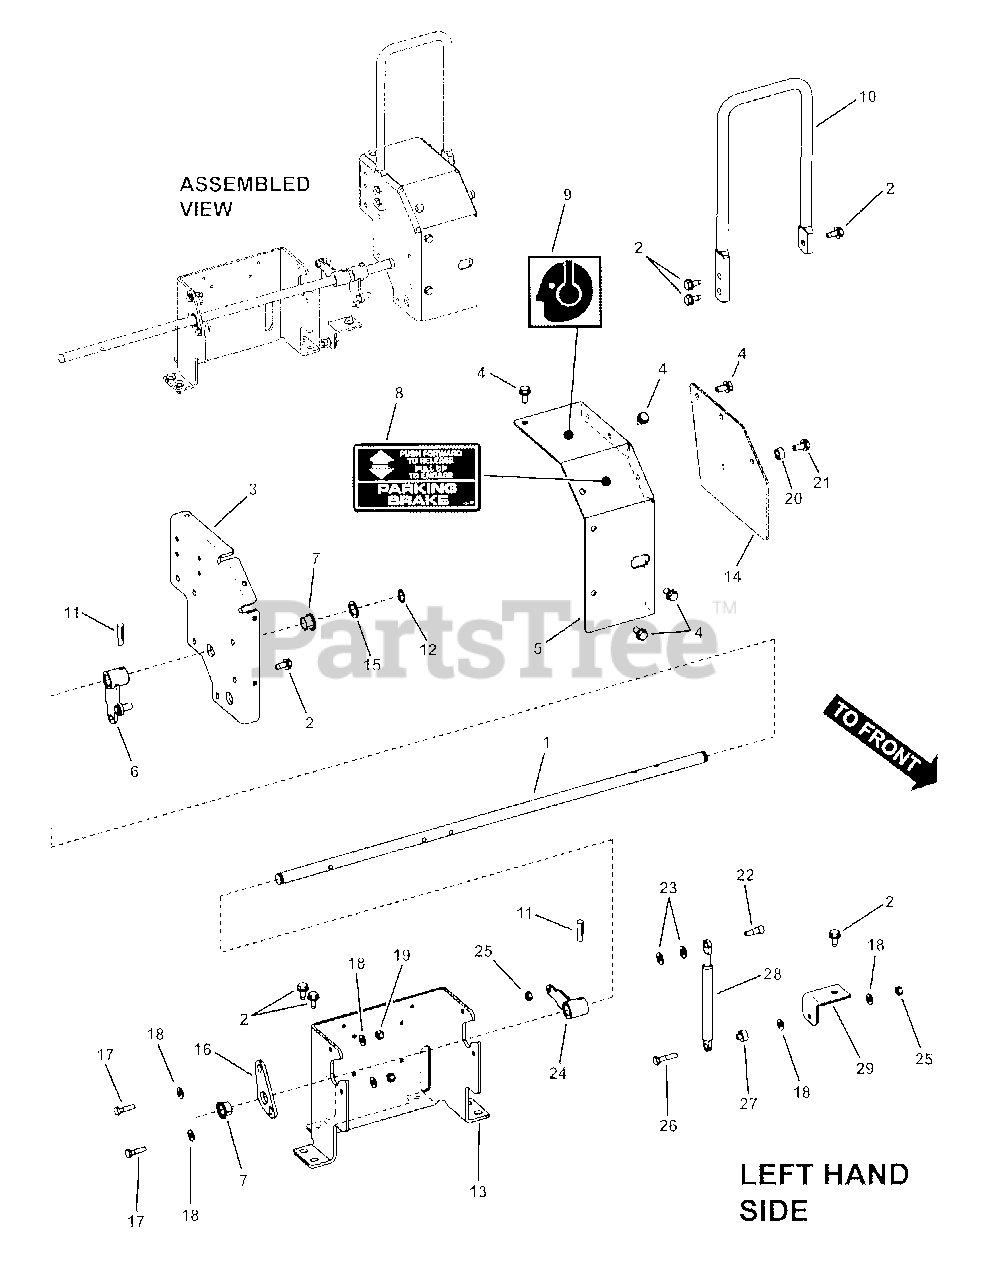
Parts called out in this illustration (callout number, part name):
1	SHAFT, Pivot
2	SCREW, 5/16-18 x 5/8" Hex Washer Self-Tap
3	MOUNT, Bearing, Left Hand
4	SCREW, 5/16-18 x 5/8" Hex Washer Self-Tap Yellow Zinc
5	LIMITER BRACKET, Left Hand
6	WELDMENT, Bellcrank
7	BUSHING, Teflon Impregnated
8	DECAL, Parking Brake
9	DECAL, Ear Protection
10	HANDLE, Support
11	GROOVE PIN, 1/4 x 1-1/4"
12	RING, 5/8" External Retaining
13	CHANNEL, Joystick Mounting
14	COVER, Left Hand Outside
15	WASHER, 5/8" Flat
16	BRACKET, Bearing Support
17	SCREW, 1/4-20 x 1" Hex Head Cap, GR 5
18	WASHER, .28 x .63 x .06 Flat
19	NUT, 1/4-20 HEX NYLON LOCK
20	SPACER, .340 I.D. x .63 O.D. x .310 Thick
21	SCREW, 5/16-18 x 3/4" Hex Washer Self-Tap
22	SHOULDER BOLT, 1/4-20 thread
23	WASHER, .34 x .69 x .08 Flat
24	BELLCRANK, Dampener (weldment)
25	NUT, 1/4-20 Hex Center Lock
26	SCREW, 1/4-20 x 1-1/4" Hex Head Cap
27	SPACER, Twin Stick
28	DAMPENER, Hydraulic
29	BRACKET, Dampener
